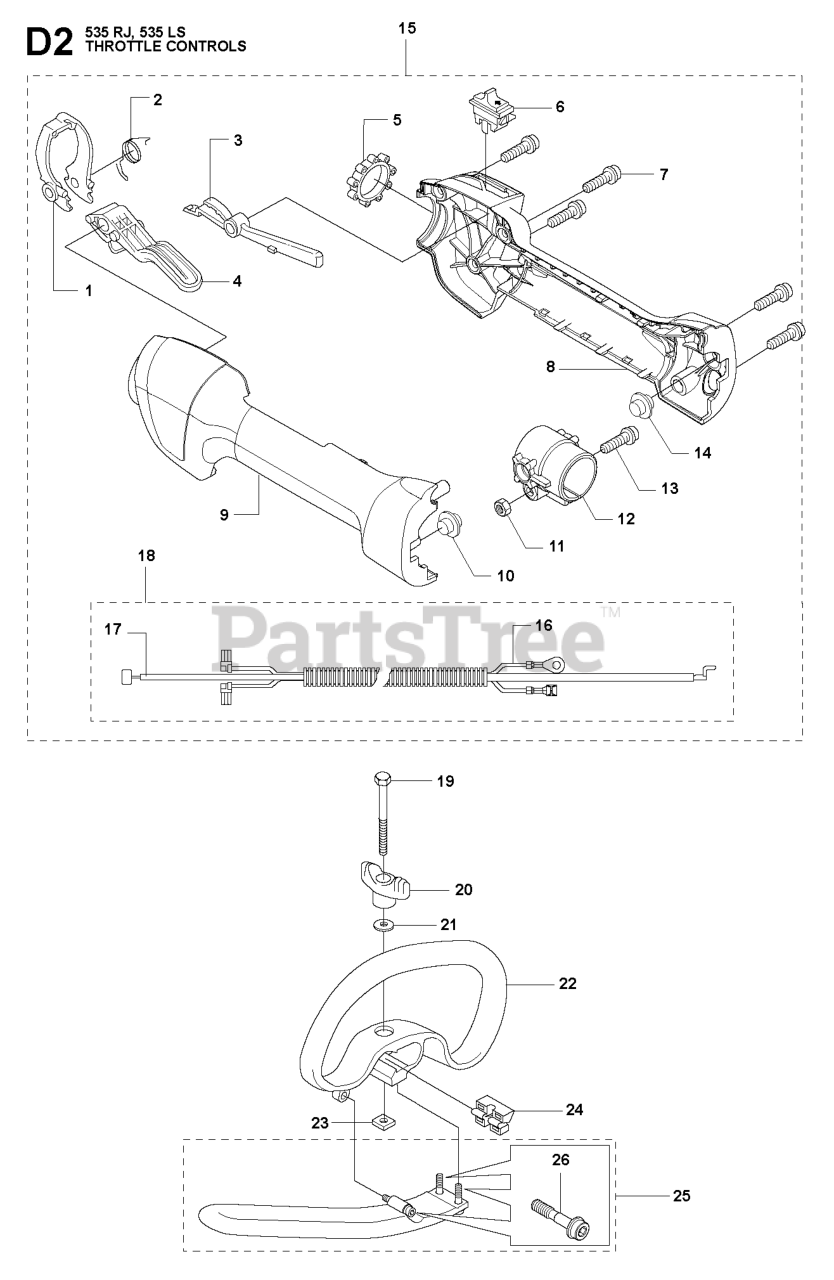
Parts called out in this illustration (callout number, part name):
2	RETURN SPRING
3	THROTTLE LOCK
4	THROTTLE TRIGGER
5	VIBRATION DAMPER
6	STOP BUTTON
8	HANDLE
9	HANDLE
10	VIBRATION ABSORBER
14	VIBRATION ABSORBER
15	THROTTLE HANDLE CPL
16	SHORT CIRCUIT CABLE
17	THROTTLE WIRE ASSY
18	WIRING ASSY.
19	SCREW M6X50
22	HANDLE.LOOP
25	HANDLE EXTENSION
26	SCREW IHSCFTO
